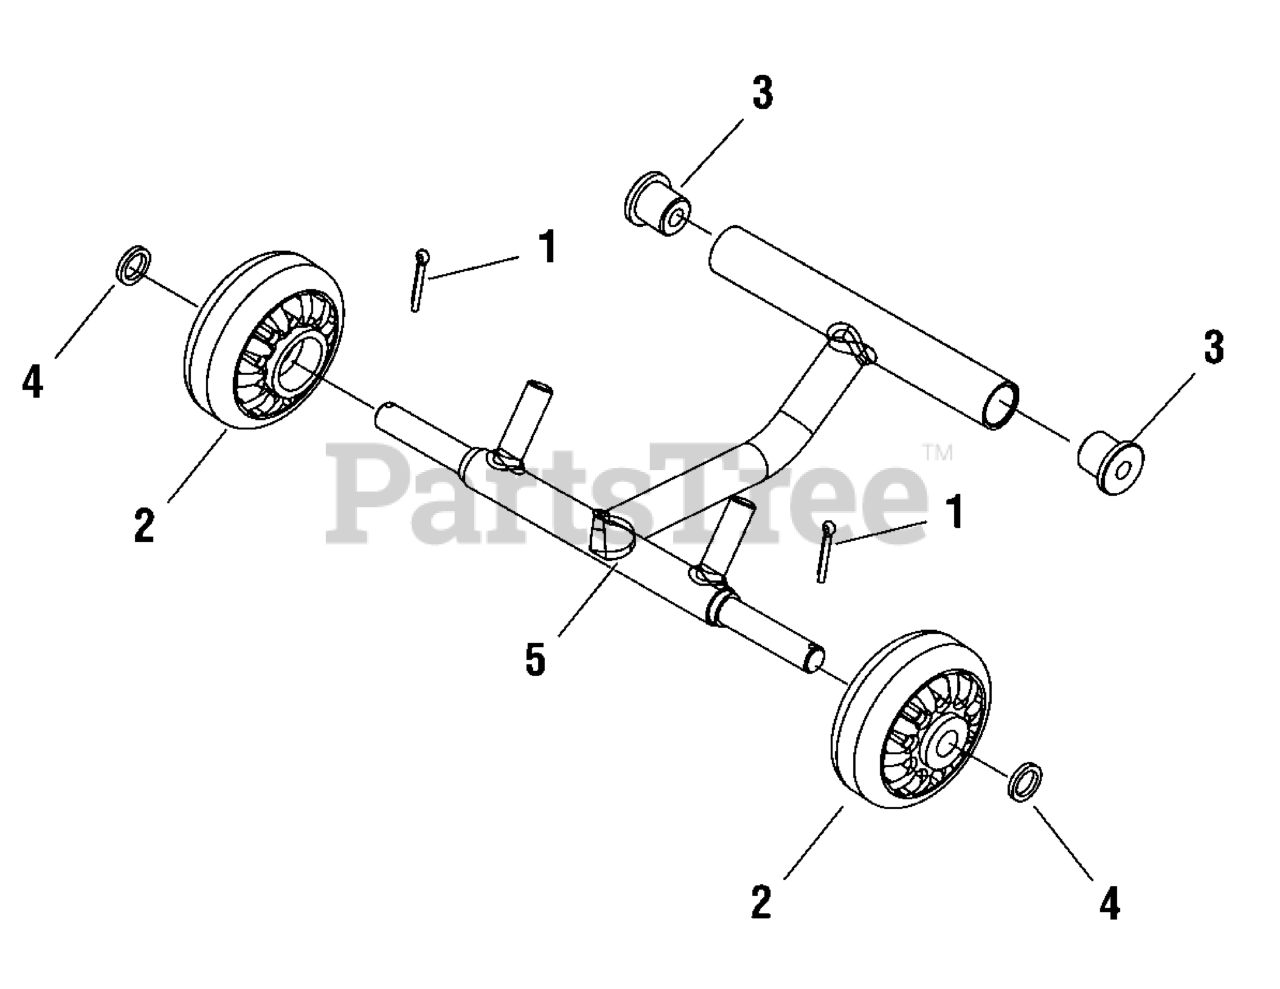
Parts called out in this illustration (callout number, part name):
1	PIN, Split
3	BUSHING, Nylon
4	WASHER
5	FRAME, Wheel
